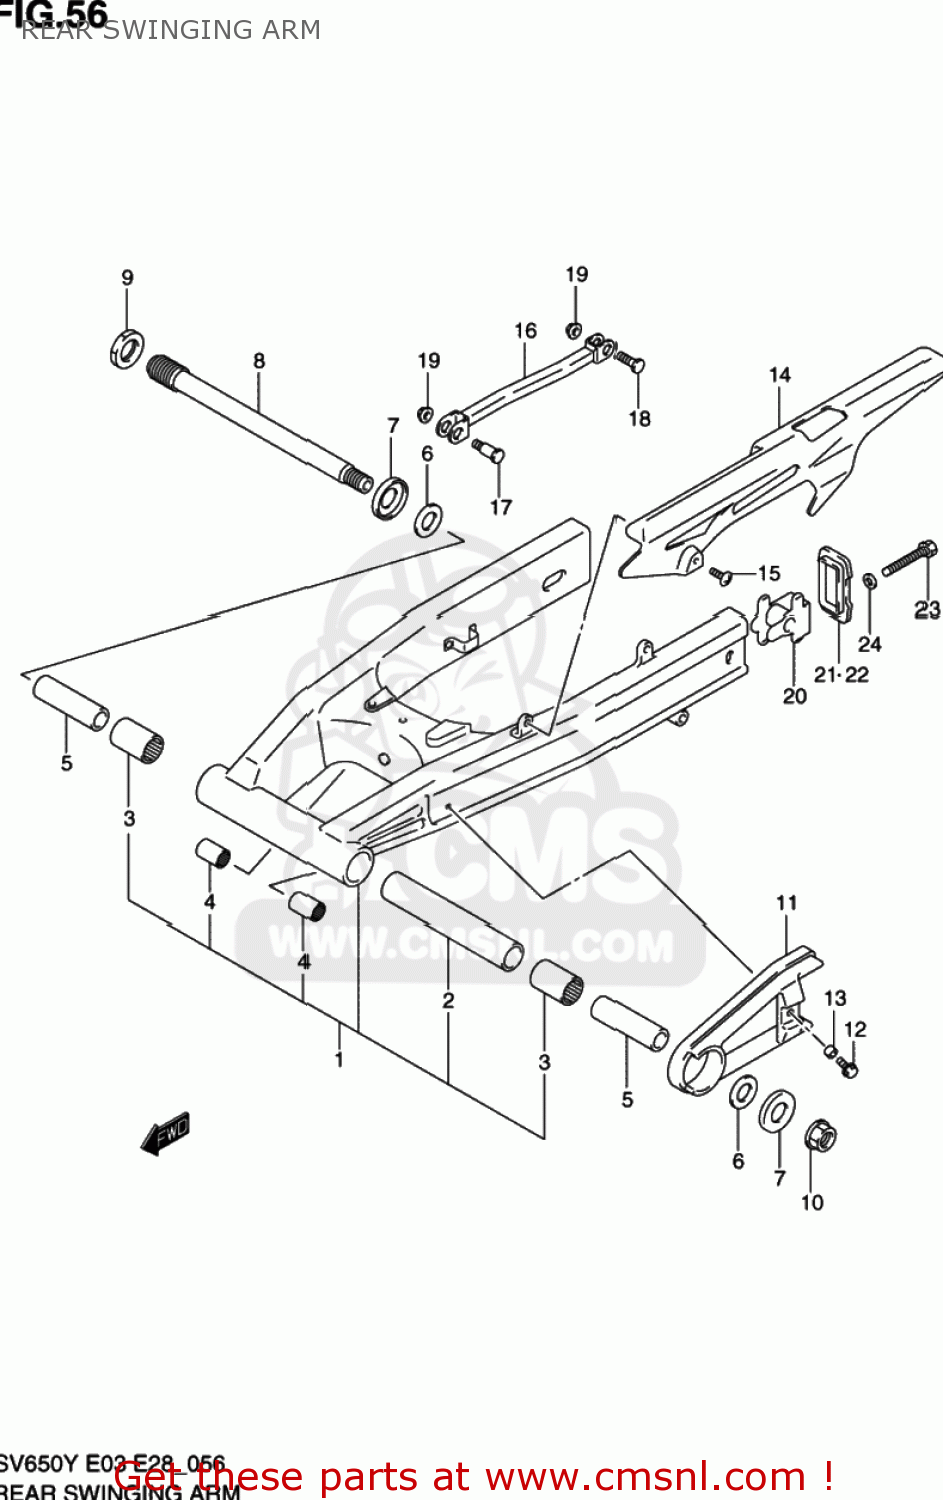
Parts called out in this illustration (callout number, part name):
1	SWINGINGARM ASSY,RR
2	SPACER,RR SWGARM PIVOT CTR
3	BEARING(25X33X30)
4	BEARING(20X27X23.5)
5	SPACER,RR SWGARM PIVOT
6	WASHER
7	DUST SEAL,RR SWGARM PIVOT
8	SHAFT,RR SWINGINGARM PIVOT
9	NUT,REAR SWING ARM PIVOT BOLT
10	NUT ,18MM
11	BUFFER,CHAIN TOUCH DEFENSE
12	BOLT(6X20)
13	SPACER(6.5X10X7)
14	CASE,CHAIN
15	SCREW(6X16)
16	TORQUELINK,RR
17	BOLT(10X39)
18	BOLT(10X34)
19	NUT
20	ADJUSTER,CHAIN
21	PLATE,CHAIN ADJUSTER GUIDE,R
22	PLATE,CHAIN ADJUSTER GUIDE,L
23	BOLT(8X50)
24	WASHER
